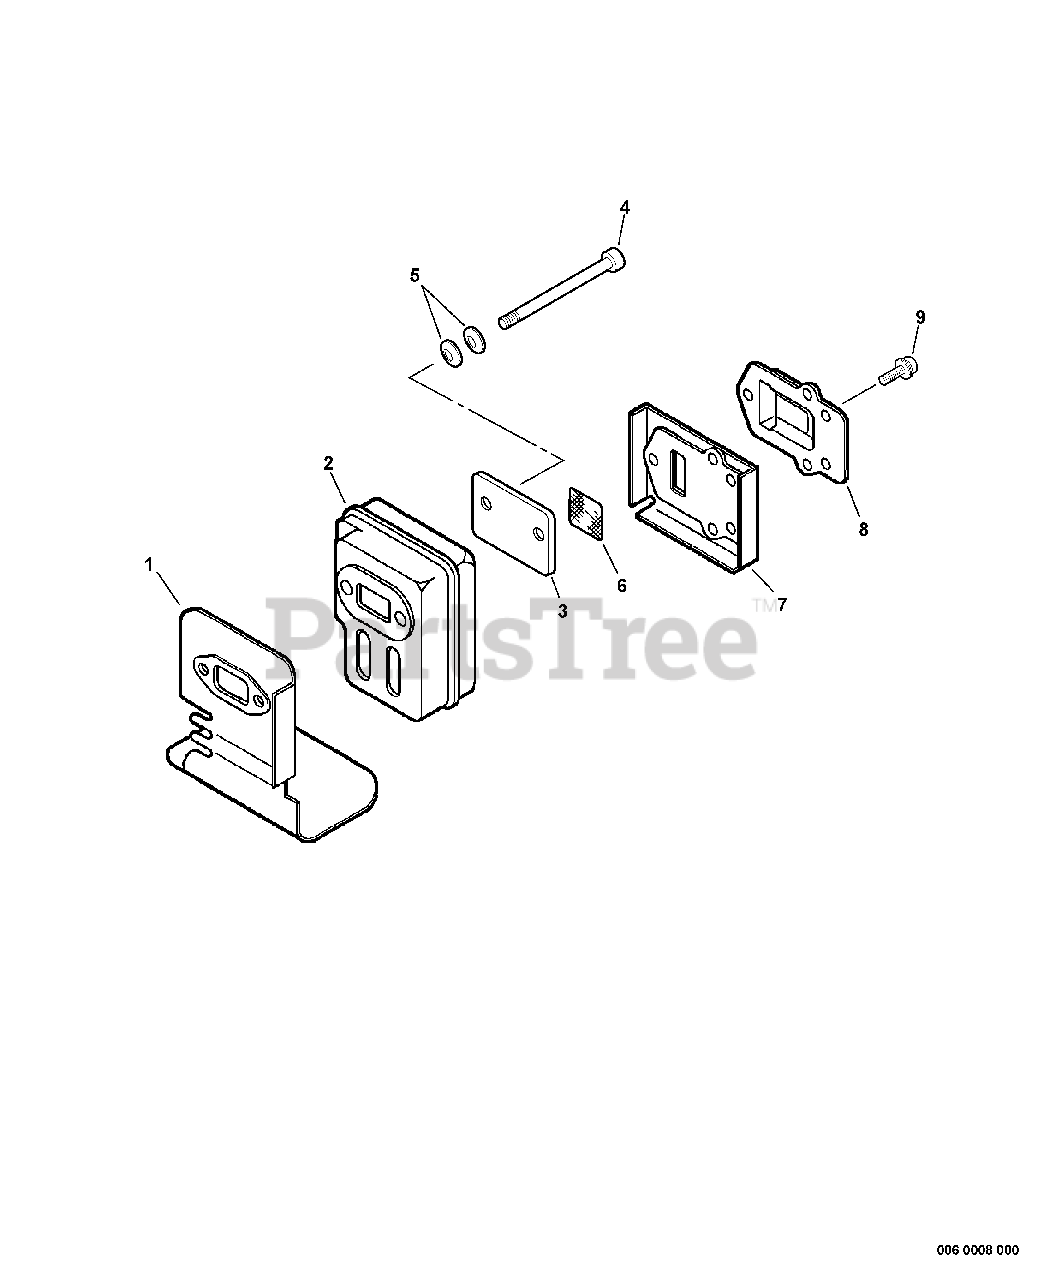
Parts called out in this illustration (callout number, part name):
1	SHIELD, EXHAUST
2	MUFFLER
3	PLATE, EYE
4	BOLT 5×55
5	CONICAL WASHER
6	SCREEN, SPARK ARRESTER
7	GASKET, EXHAUST
8	GUIDE, EXHAUST
9	SCREW 4×10
